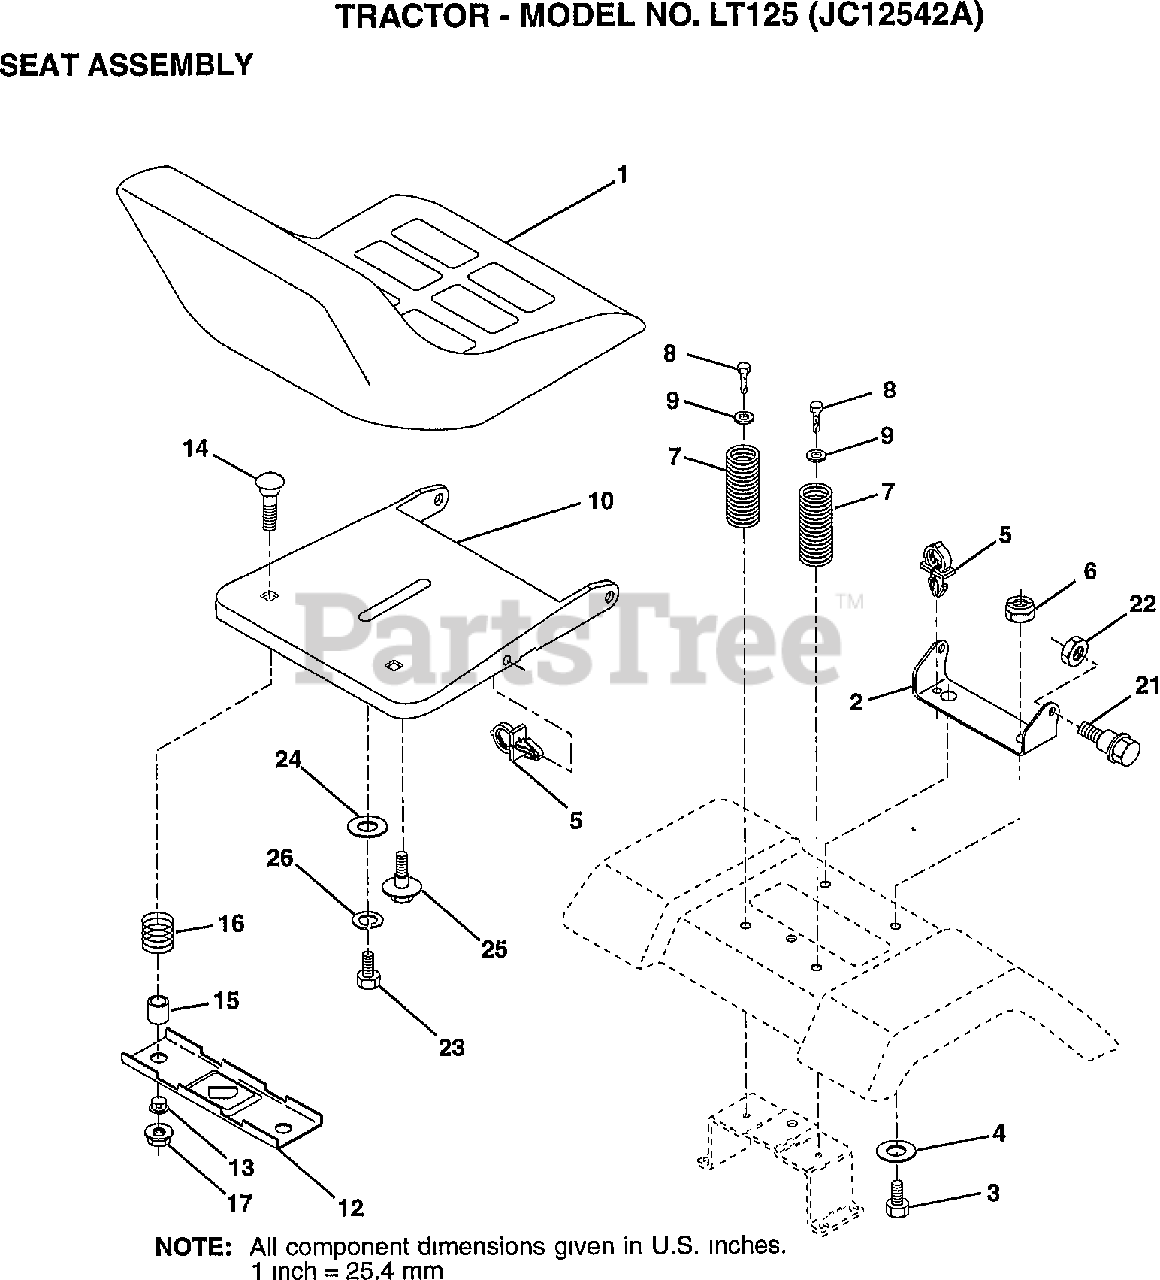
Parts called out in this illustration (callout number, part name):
3	BOLT FIN HEX 3/8-16 X 1
4	WASHER 13/32 X 1 X 10 GA
6	LOCKNUT
8	SCREW THDROL 3/8-16 X 1 TY-TT
9	WASHER 13/32 X 1 X 14 GA
14	BOLT RDHD SQNK 1/4-20X 1-3/8
22	LOCKNUT
23	BOLT FIN HEX 1/2-13 X 7/8 GR 5
24	WASHER 17/32 X 1-3/16 X 12 GA
26	WASHER LOCK HVY HLCL SPR 1/2
